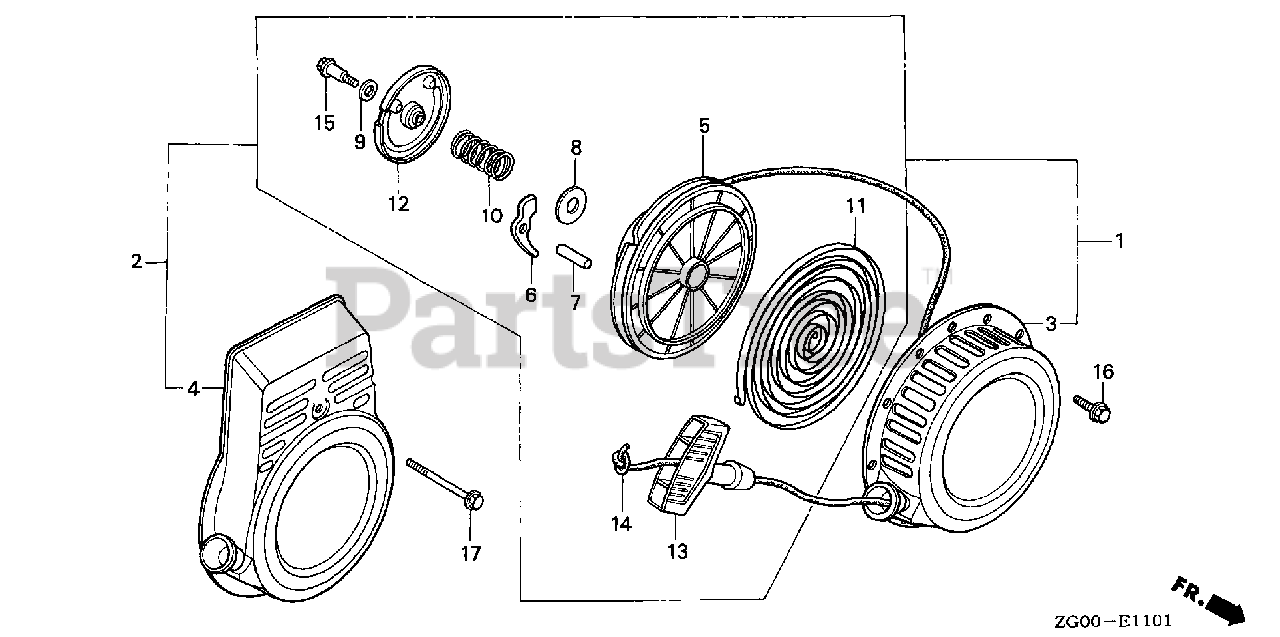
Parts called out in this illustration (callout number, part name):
1	STARTER, RECOIL
3	CASE, STARTER
5	REEL, STARTER
6	RATCHET, STARTER
7	SHAFT, RATCHET
8	PLATE A, FRICTION
9	PLATE B, FRICTION
10	SPRING, FRICTION
11	SPRING, RETURN
12	COVER, REEL STARTER
13	GRIP, STARTER
14	ROPE, STARTER (#4X65") (N/A: USE P/N 08540-ZG921-11)
15	BOLT, REEL COVER
16	BOLT, FLANGE (6X8)
